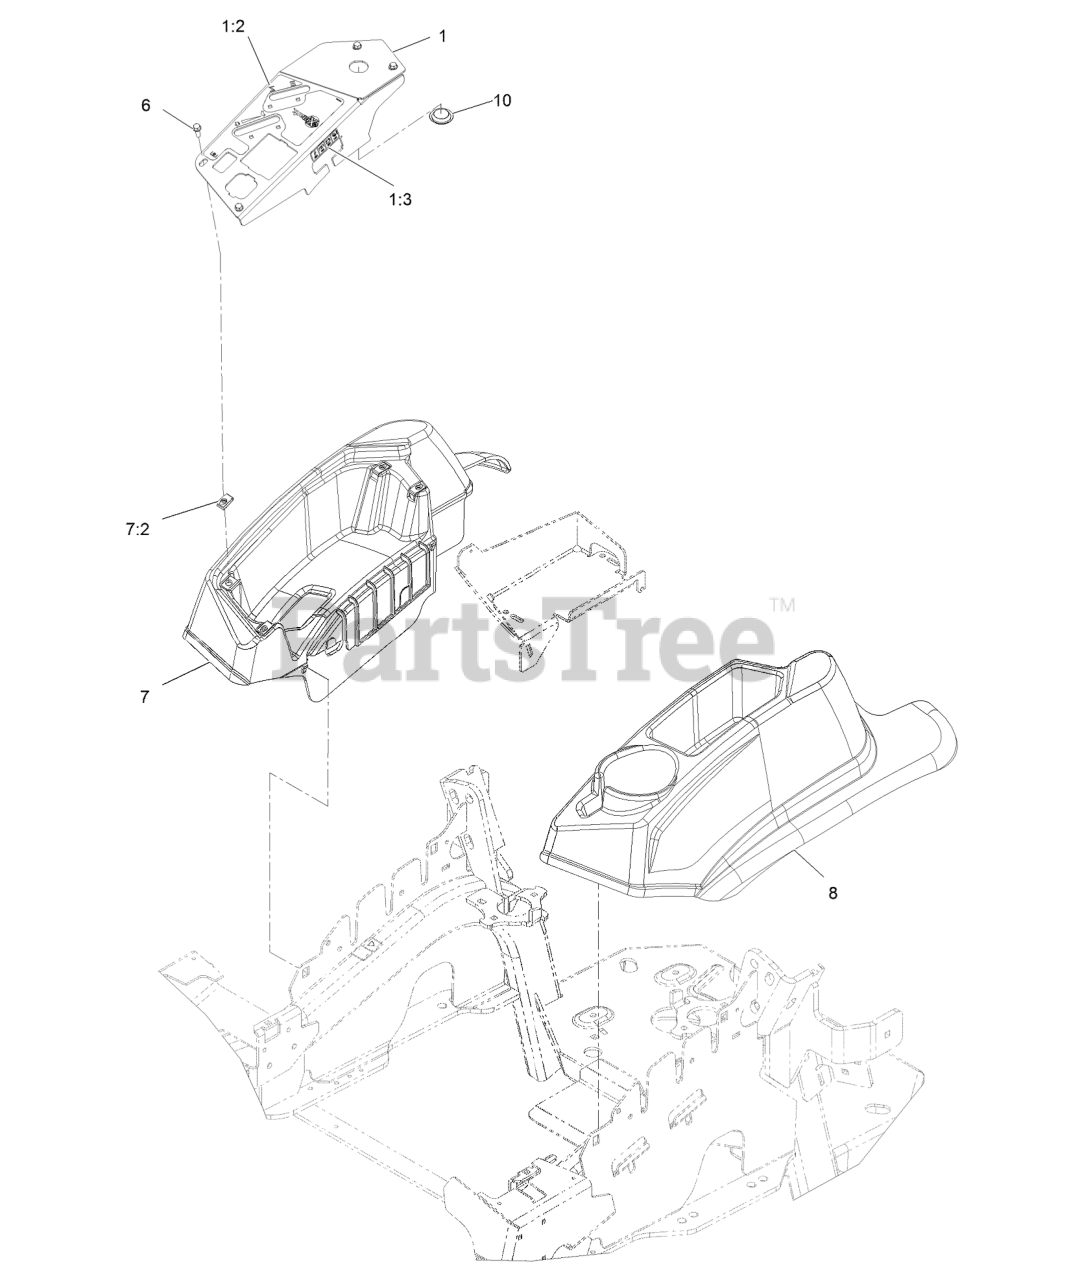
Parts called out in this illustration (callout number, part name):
1	CONSOLE,PANEL W/DECAL
1:2	DECAL-CONTROL PANEL NON-E
1:3	DECAL-FUSES
2	ASM, CHOKE CABLE
3	ASM,THROTTLE CABLE
4	BOLT-CARR
5	NUT-LOCK, NI
6	SCREW-HWH
7	CONSOLE,RH AS ASM
8	CONSOLE, LH AS
9	CLAMP-HOSE
10	PLUG-PLASTIC
